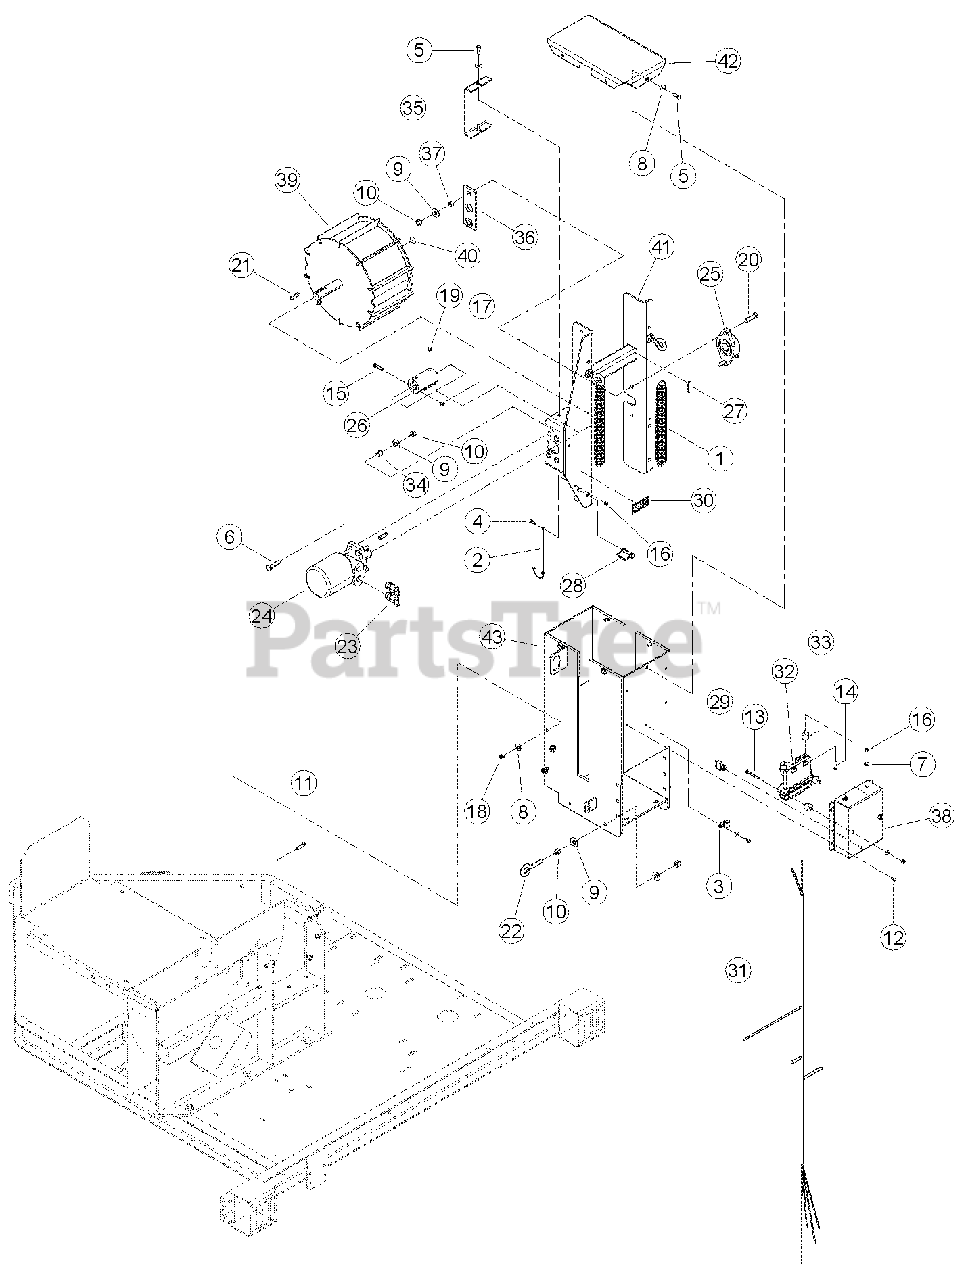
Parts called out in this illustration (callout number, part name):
1	SPRING, EXTENSION
2	LANYARD, NYLON
3	CLAMP, 9/16 COATED
4	BOLT, 1/4 X 3/4 HEX HD GR5 ZP
5	BOLT, 3/8 X 1 HEX HD GR5 ZP
6	BOLT, 1/2 X 2 HEX HD GR5 ZP
7	WASHER, 1/4 FLAT ZP
8	WASHER, 3/8 FLAT ZP
9	WASHER, 1/2 FLAT ZP
10	NUT, 1/2 CENTERLOCK GRB ZP
11	BOLT, 3/8 X 1-1/2 CRG GR5 NC ZP
12	BOLT, 1/4 X 1/2 HCS GR5 ZP
13	BOLT, 1/4 X 2-1/4 HCS GR5 ZP
14	BOLT, 1/4 X 1-1/4 HCS GR5 ZP
15	BOLT 5/16 X 1-1/2 HEX HD GR5 ZP
16	NUT, 1/4 NE NYLOCK ZP
17	NUT, 5/16 NE NYLOCK ZP
18	NUT, 3/8 NE NYLOCK ZP
19	SET SCREW, 3/8 X 1/2 CUP PT SKT
20	BOLT, 1/2 X 1-3/4 HCPS GR5 NC ZP
21	KEY, 5/16 X 1-1/2 SQUARE
22	I-BOLT, 1/2 X 2 ZP
23	ADAPTER, -10 MORING / -8 MJIC 45 DEG.
24	MOTOR, 45 CU. IN. HYDRAULIC
25	BEARING, 1-1/4 DIA. 2 BOLT FLANGE
26	COUPLER, 1-1/4 SHAFT
27	WEAR PAD, STD. SPRING HD FRONT
28	PIN, SHAP 3/8 X 1-1/2 USEABLE LENGTH
29	CIRCUIT BREAKER, 10 AMP RESETTABLE
30	DECAL, CRUSHING ISO
31	HARNESS, 9" DIESEL PLUS 1 CONTROLLER
32	CONTROLLER, PLUS 1 CHIPPER
33	BUMPER, 1 OD. W/1-1/4 STUD
34	SPACER, .75 X .62
35	SHIELD, COUPLER
36	BEARING, SLIDE
37	SPACER, .75 OD. X .5 ID. X .37
38	ENCLOSURE, PLUS 1 MOUNT
39	ASSEMBLY, TOP GRAB ROLLER SERVICE PART
40	DECAL, ROTATING SHAFT
41	WELDMENT, ROLLER SLIDE
42	WELDMENT, TOP ROLLER COVER
43	WELDMENT, ROLLER SUPPORT
